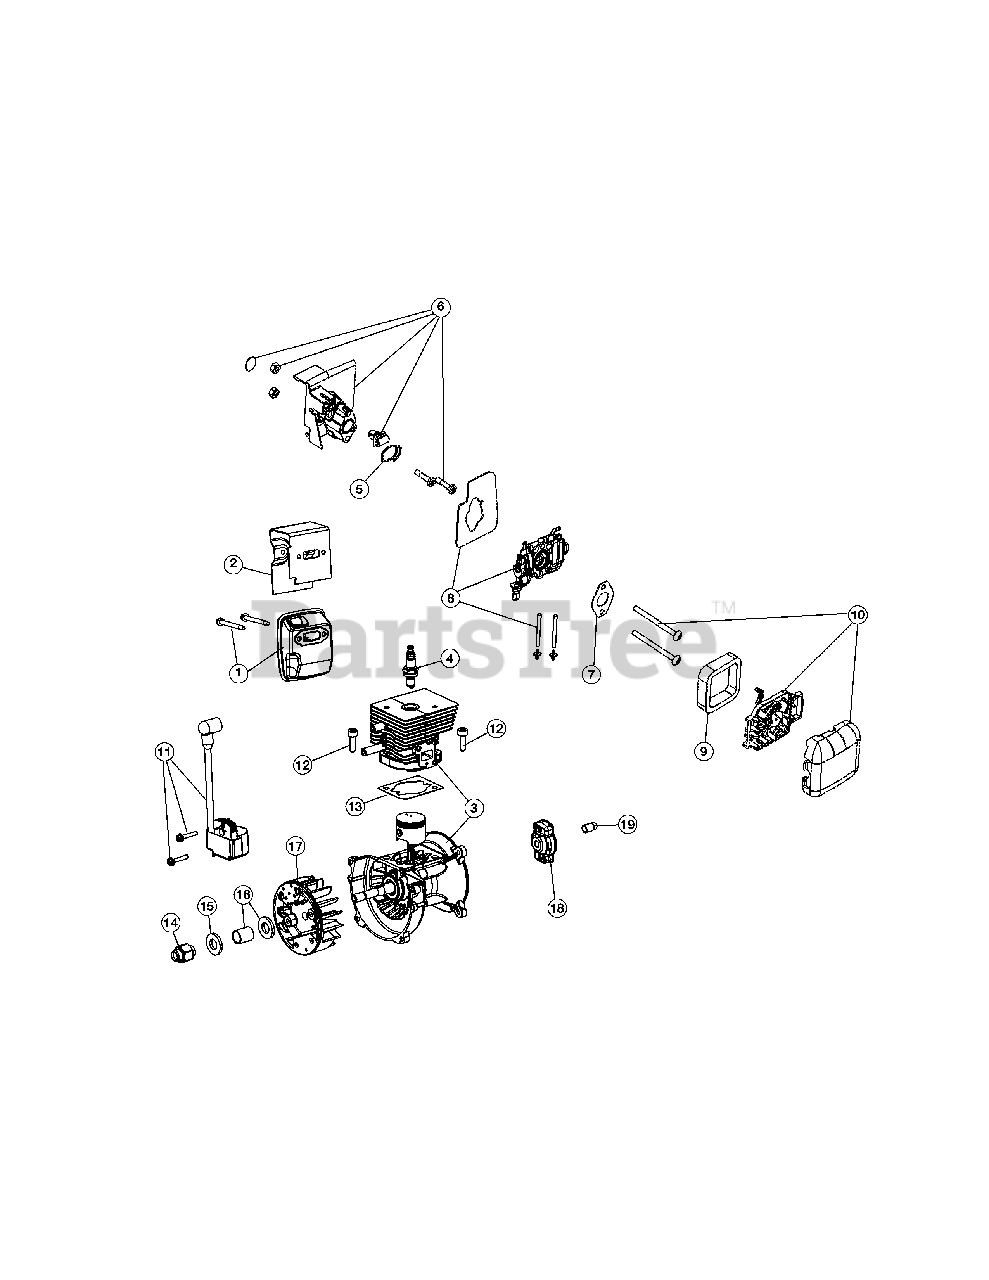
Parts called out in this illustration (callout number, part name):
1	Muffler Assembly
2	Muffler Gasket
3	Shortblock Assembly
4	Spark Plug
5	Insulator O-Ring
6	Insulator Assembly
7	Carburetor Gasket
8	Carburetor Assembly
10	Air Cleaner Assembly
11	Module Assembly
13	Cylinder Gasket
14	Flywheel Adaptor
15	Washer
17	Flywheel Assembly
18	Pawl Assembly
19	Electric Start Adaptor
